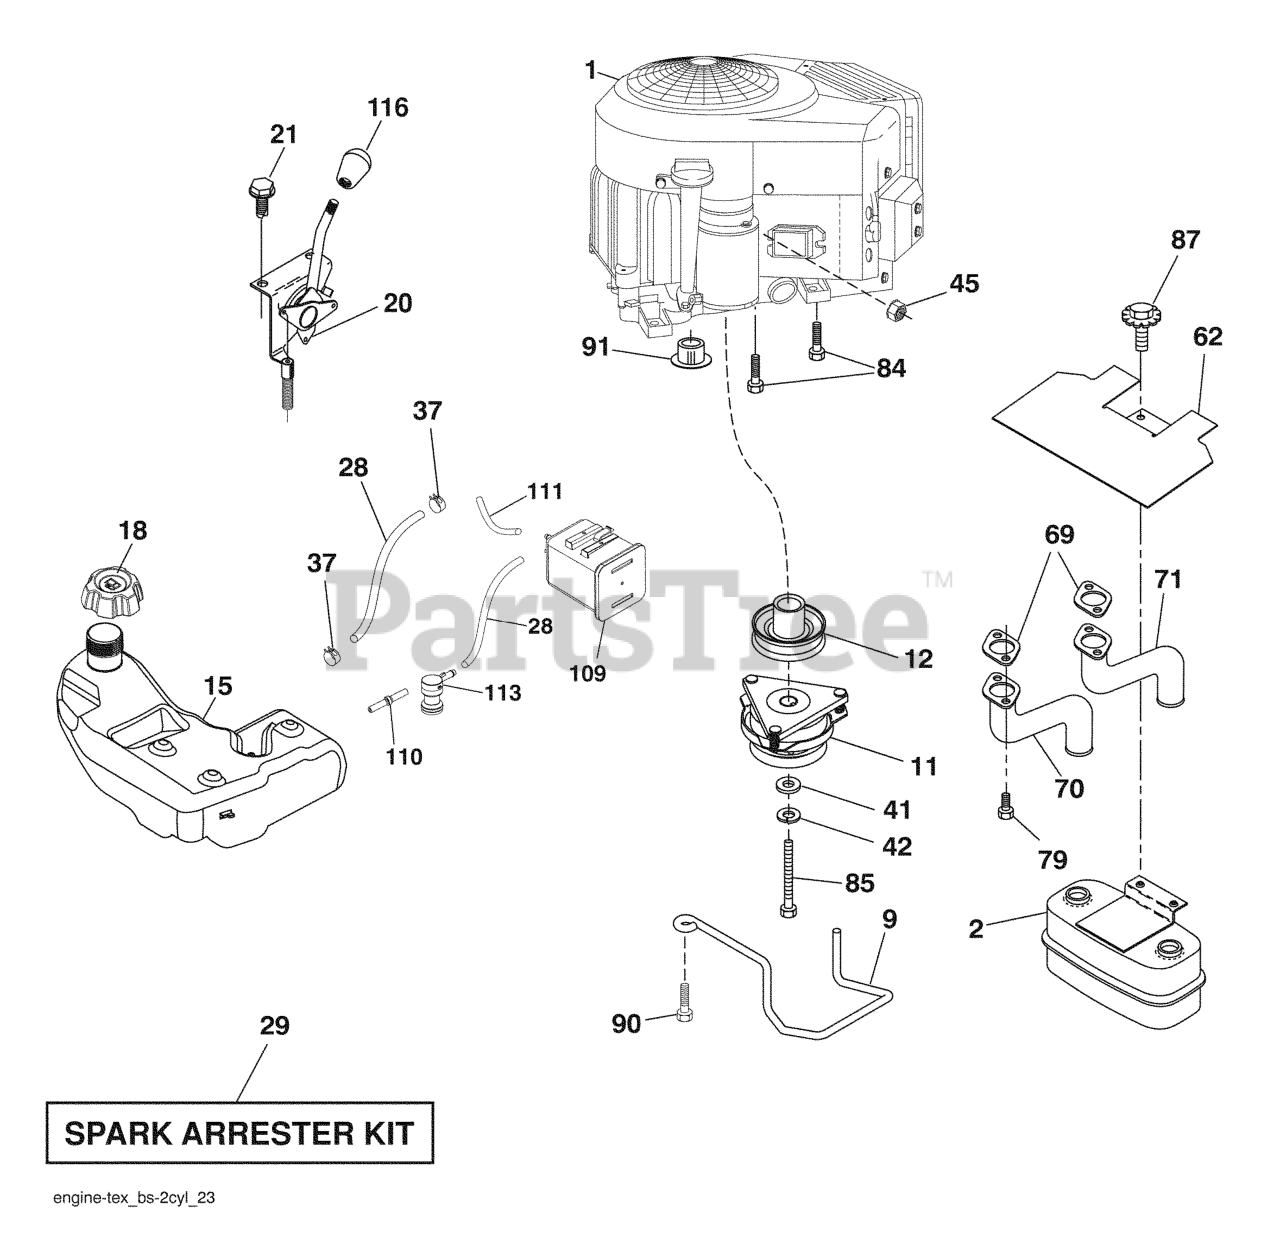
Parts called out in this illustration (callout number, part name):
2	MUFFLER.TWIN.CYL.LOW.TONE
9	KEEPER.BELT.ENGINE.4.2
11	CLUTCH MZ ZTR GT.48/54"1.125"
12	PULLEY.ENGINE.TUFFTORQ
15	TANK.ASM.FUEL.3GA.CARB
18	CAP ASM
20	CONTROL THROTTLE/CHOKE
21	SCREW.#10 X 0.750.BOS
28	LINE.FUEL.64"REAR.EMIS
29	KIT.SPARK ARRESTOR 794945 B&S
37	HOSE CLAMP
42	LOCKWASHER
45	NUT
62	RP SHIELD HEAT MUFFLER
69	GASKET.MUFFLER
70	RP.EXHAUST.TUBE.LH.BS/TWIN
71	EXHAUST.TUBE.RH.BS/TWIN
79	SCREW.SOCKET.HEAD.5/16-18
84	SCREW.3/8-16
85	BOLT HEX 7/16-20X4-1/4"
87	BOLT.5/16-18UNCX3/4 W/SEMS.BLK
90	SCREW 3/8-16X1
91	BUSHING.1.375OD
109	CANNISTER, CARBON
110	VALVE.ASM.ANTI-SLOSH
111	RP PURGE LINE
113	VALVE.SLANT.CARTRDG.90 DEG.TEX
116	RP KNOB SOFT TOUCH
